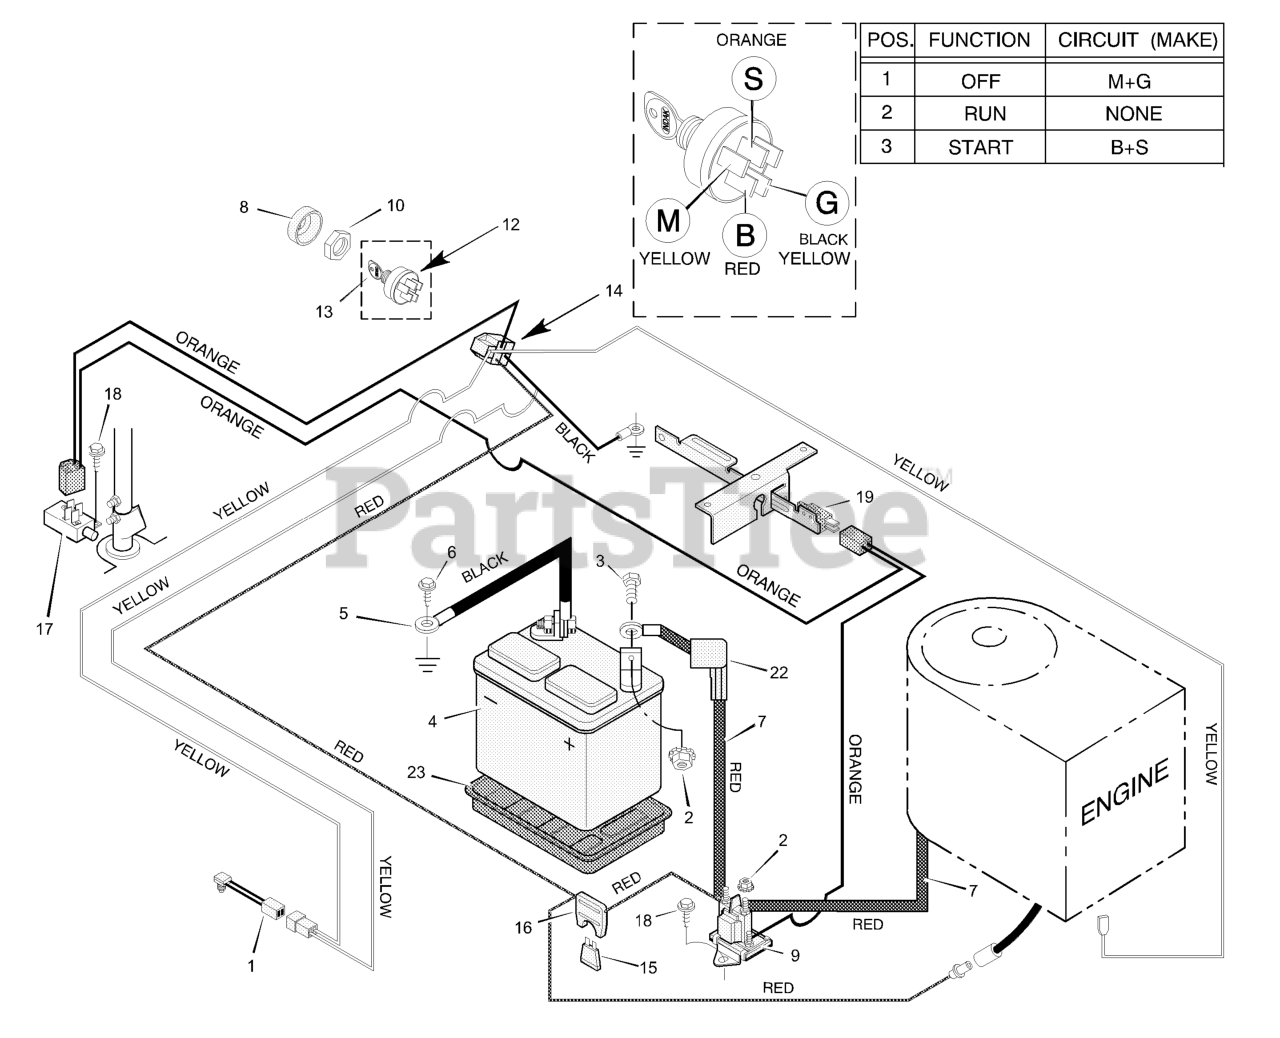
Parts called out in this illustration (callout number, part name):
1	Switch, Seat Sensor
2	Locknut
3	BOLT, Hex
4	Battery
5	CABLE, Battery Ground (Black)
7	CABLE, Positive Battery (Red)
8	Cap, Ignition Switch
9	Solenoid
10	NUT, Ignition Switch
12	Switch, Ignition
13	Key, Ignition
14	Harness, Wire
16	Holder, Fuse
17	Switch, Attachment Clutch
19	Switch, Limit
22	Cover, Terminal
23	Tray, Battery
